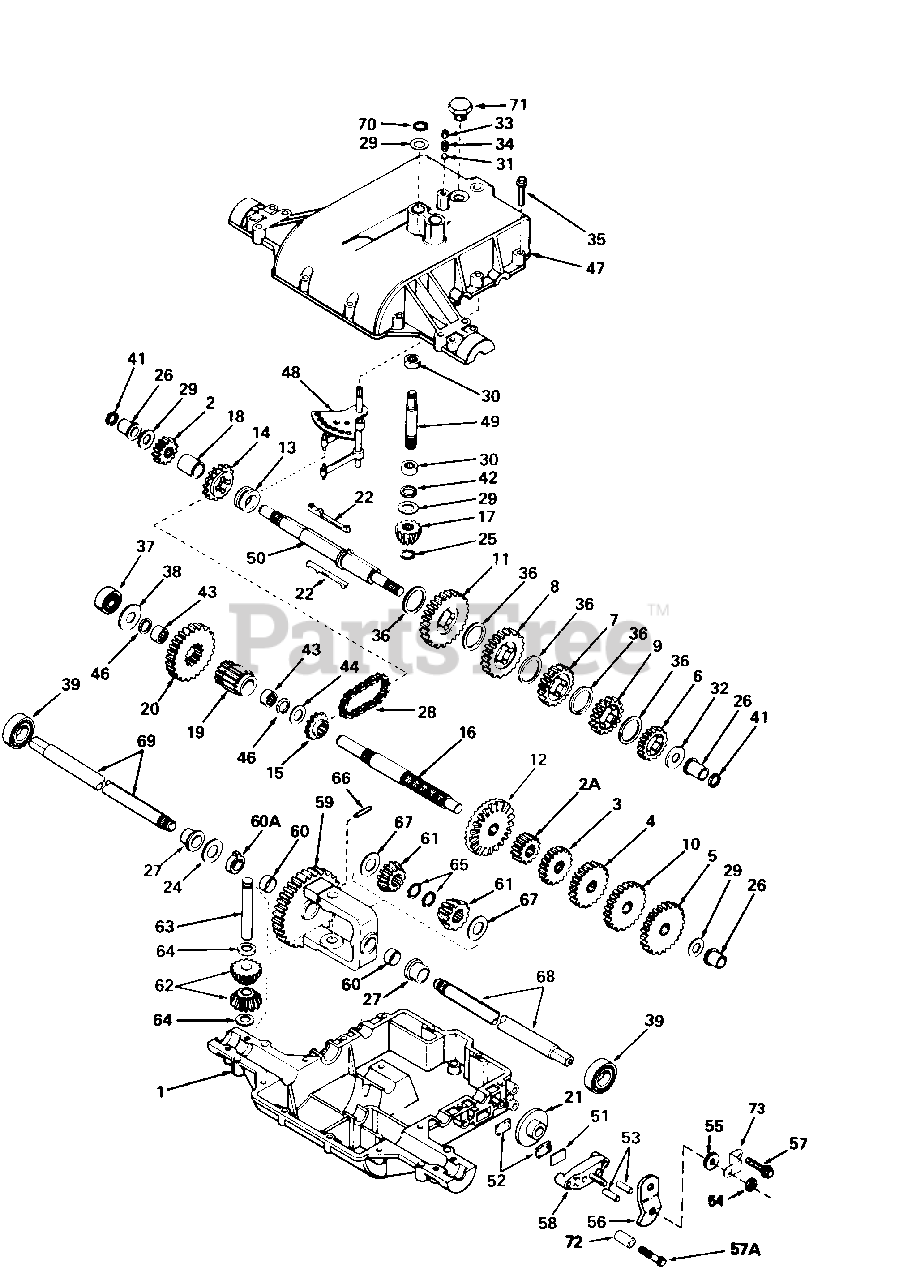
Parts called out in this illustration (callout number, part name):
1	Case, Transaxle
2	Gear, Spur (15 teeth)
2A	Gear, Spur (12 teeth)
3	Gear, Spur (20 teeth)
4	Gear, Spur (25 teeth)
5	Gear, Spur (30 teeth)
6	Gear, Spur (20 teeth)
7	Gear, Spur (25 teeth)
8	Gear, Spur (30 teeth)
9	Gear, Spur (22 teeth)
10	Gear, Spur (28 teeth)
11	Gear Spur (37 teeth)
12	Gear, Bevel (42 teeth)
13	Collar, Shift
14	Sprocket (18 teeth)
15	Sprocket (9 teeth)
16	Shaft, Counter
17	Bevel Pinion, Input
18	Spacer
19	Pinion, Output
20	Gear, Output
21	Disk, Brake
22	Key
24	Washer
25	Ring, Retaining
26	Bushing, Flanged
27	Bushing, Flanged
28	Chain, Roller (No. 41 Chain, 24 Links)
29	Washer, Thrust
30	Bearing, Needle
31	Ball, Steel
32	Washer, Thrust
33	Screw, Set, 3/8-16 x 3/8
34	Spring
35	Screw, Hex Hd. Thread Forming, 1/4-20 x 11/4
36	Washer, Thrust
37	Bearing, Ball
38	Washer, Flat
39	Bearing, Ball
41	Ring, Square Cut
42	Ring, Square Cut
43	Bearing, Needle
44	Washer, Flat
46	Ring, Square Cut
47	Cover, Transaxle
48	Rod & Fork Ass'y., Shift
49	Shaft, Input
50	Shaft, Brake
51	Plate, Brake Pad
52	Pad, Brake
53	Pin, Dowel
54	Locknut, 5/16-24
55	Washer, Flat
56	Lever, Brake
57	Screw, Hex Hd. Thread Forming, 1/4-20 x 11/4
57A	Screw, Hex Hd. Thread Forming, 1/4-20 x 21/4
58	Holder, Brake Pad
59	Gear Ass'y., Differential
60	Bushing
60A	Bushing
61	Gear, Bevel
62	Pinion Bevel
63	Pin, Drive
64	Washer, Thrust
65	Ring, Retaining
66	Pin, Roll
67	Washer, Thrust
68	Axle (15-1/4" Long)
69	Axle (13-3/8" Long)
70	Ring, Retaining
71	Plug, Hex Hd., 9/16-18 Thread
72	Spacer
73	Bracket, Brake Lever
